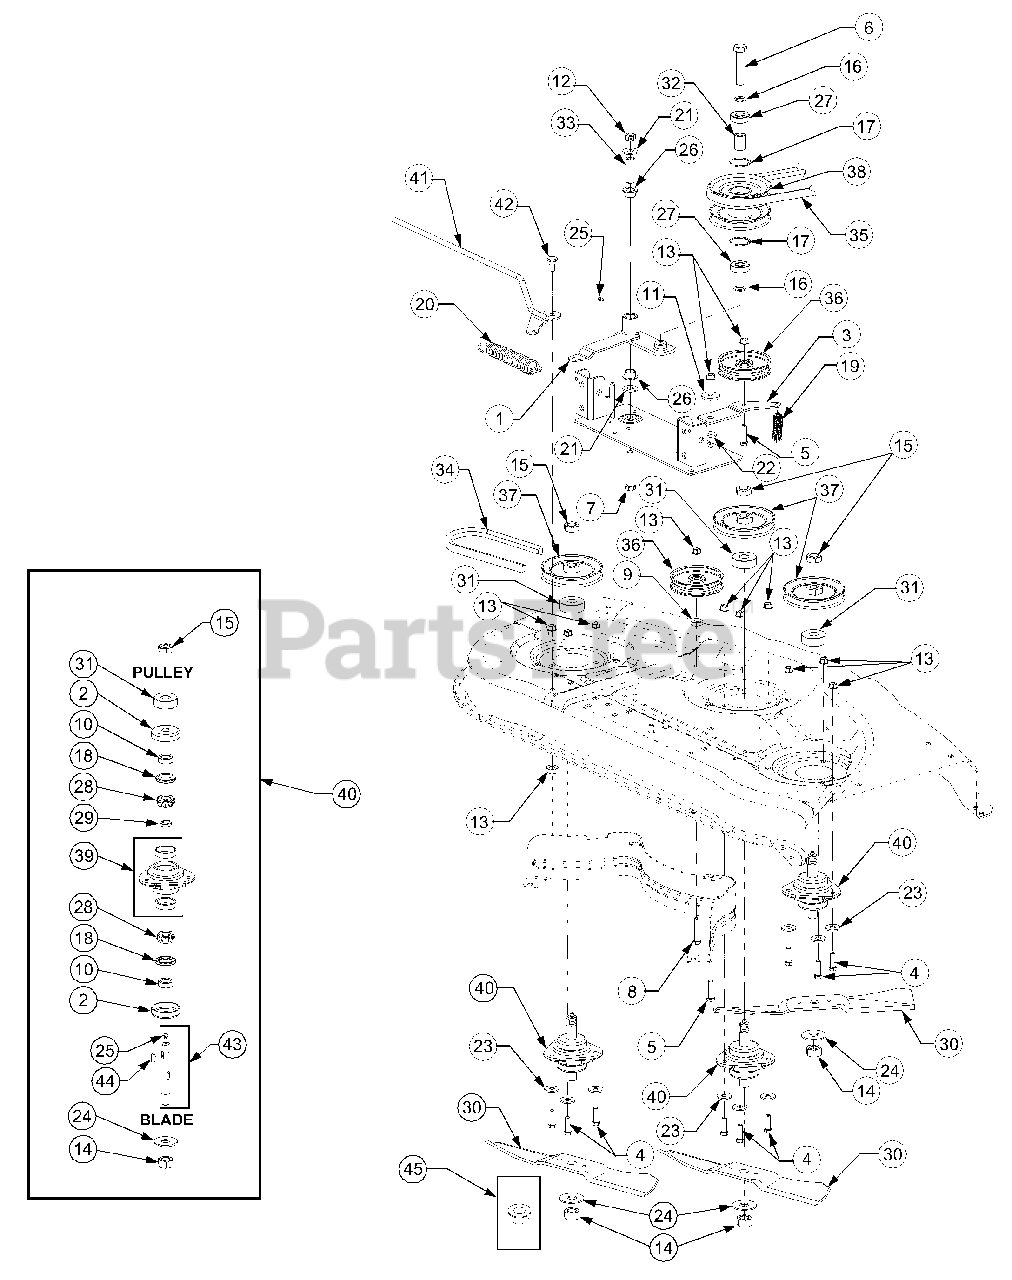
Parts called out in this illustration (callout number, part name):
1	Pivot Arm, Double Pulley
2	Cup, Spindle
3	Arm, Idler
4	Screw, Hex Cap 3/8-16 x 1.25 GR5
5	Screw, Hex Cap, 3/8-16 x 1.5 GR5
6	Screw, Hex Cap, 5/8-18 x 3 GR5
7	Screw, Hex Cap, 1/2-20 x 3 GR8
8	Screw, Hex Cap, 3/8-16 x 2
9	Spacer, .380 ID x 1 OD x .32
10	Spacer, .755 ID x 1.25 OD x .44
11	Spacer, Shoulder
12	Nut, Hex Center Lock, 1/2-20
13	Nut, Hex Flanged Lock, 3/8-16
14	Nut, Hex, 3/4-16 GR8
15	Nut, Hex Jam, 3/4-16 GR5
16	Washer, Flat, .65 x 1.25 x .075
17	Snap Ring, Internal
18	Seal, Oil, 1.25 x 1.874 x .25
19	Spring, Extension, .75 OD x 6.12
20	Spring, Extension, 1.25 OD x 8.15
21	Washer, Flat, .531 x 1.25 x .1 Thk
22	Washer, Flat, .385 x 1 x .127 Thk
23	Washer, Flat, .406 x 1.0 x .105
24	Washer, Flat, .781 x 2 x .105 Thk
25	Fitting, 3/16 Drive Lube
26	Bearing, Flange, 3/4 ID x .53
27	Bearing, Ball, .62 x 1.57 x .470
28	Cone, Bearing
29	Spacer, Bearing
30	Blade, Low Lift, 16.5"
31	Spacer
32	Spacer, Pulley, .635 ID x .88 OD x
33	Spacer, Idlr Brkt, .51 ID x .75 OD x
34	Belt, Spindle, A-Section x 105"
35	Belt, PTO, B-Section x 110.6"
36	Pulley, Flat Idler, 4.06 OD
37	V-Pulley, 4.70 OD
38	Pulley, Double
39	Housing w/Cups, Spindle
40	Spindle Ass'y, Blade
41	Handle, Tension
42	Bolt, Shoulder, .498 Dia. x .340
43	Kit, Shaft w/Seal
44	Key, #91 Woodruff, 1/4 x 3/4
45	Nut, Hex Flange, 3/4-16
